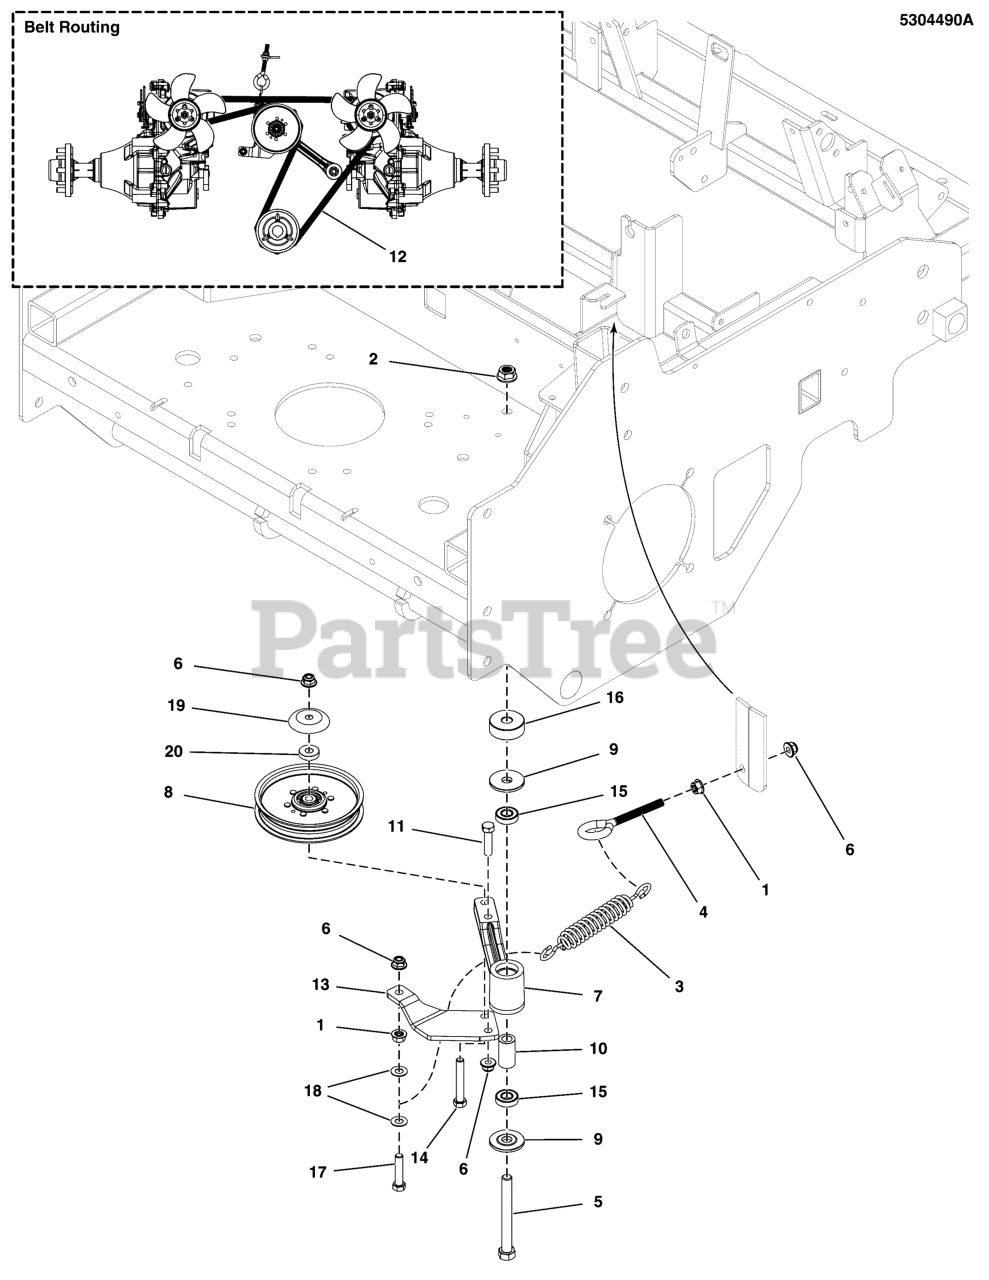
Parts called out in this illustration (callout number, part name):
1	NUT, 3/8-16 HEX SERRATED FLANGE
2	NUT, Hex Flange, Nylock, 1/2-13
3	SPRING-EXT, 1.04 ODX6.935LGX.148WR, BLK
4	EYE BOLT, 3/8-16 X 5, 2.88THRD, 1EYE, CZ
5	BOLT, 1/2-13 X 4-1/2 GD5 CZ
6	NUT, 3/8-16 HEX NYLOCK FLANGE
7	ASSM, IDLER ARM, PUMP DRIVE, 1/2ID, CAST (SV)
8	PULLEY-IDLER, 5.00OD, .385ID, .75W, STL
9	SPACER, IDLER ARM, 1/2, PM
10	SPACER, .52 X .84 X 1.53, PM
11	BOLT, 3/8-16 X 1-1/2" GD5 CZ
12	BELT, HB SEC, 81.2" EL, RAW EDGE, ARAMID
13	PLATE, IDLER ARM ADAPTER - BLK
14	BOLT, 3/8-16 X 2-3/4" GD5 CZ
15	BEARING, BALL, AXLE
16	SPACER, .52 X 1.75 X .63, CZ
17	BOLT, 3/8-16 X 1-3/4" GD5 CZ
18	WASHER, 3/8 USS
19	SHIELD, BEARING PULLEY, 3/8ID, CZ
20	SPACER, .36 X 1.00 X .25, PM, CZ
